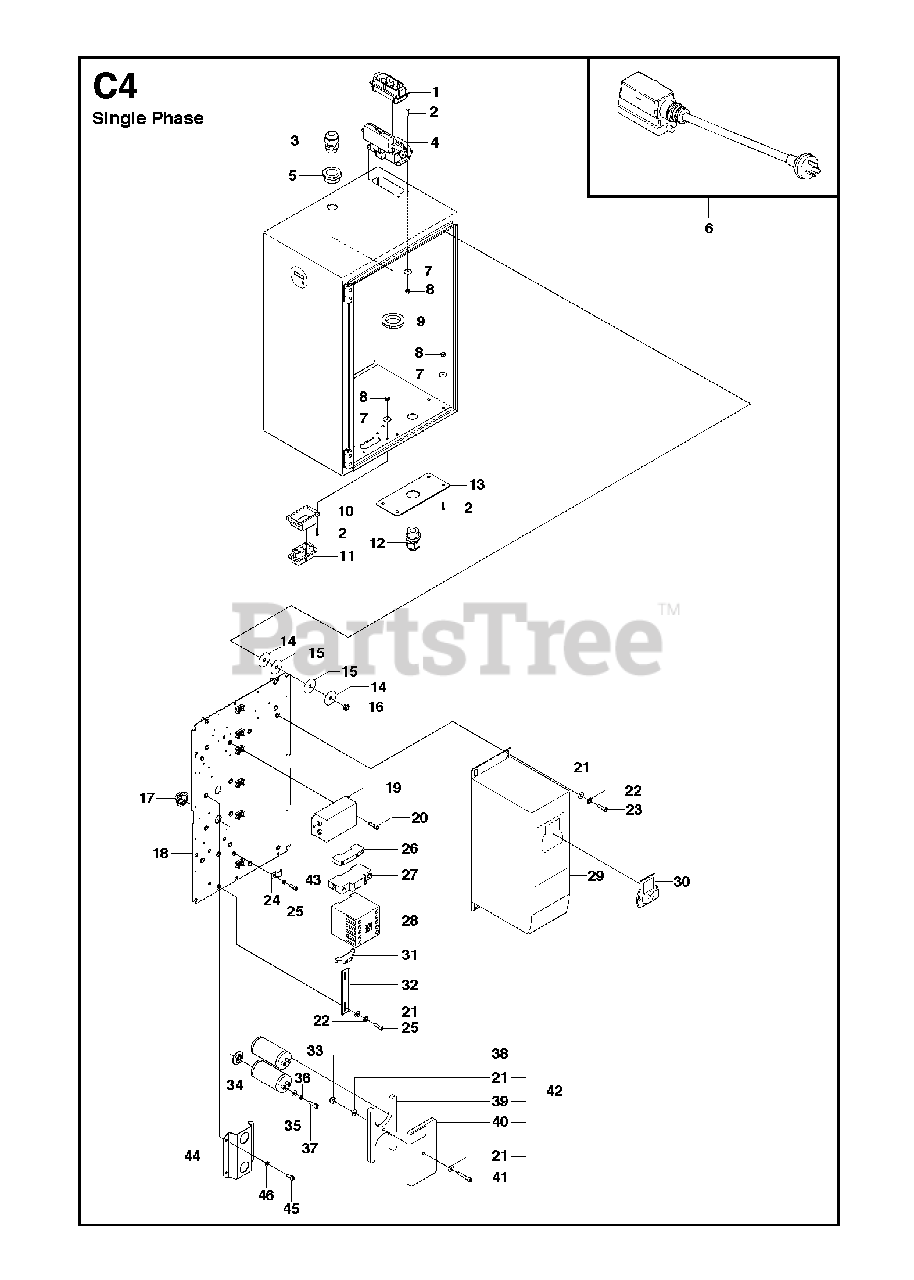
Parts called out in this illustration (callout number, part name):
2	SCREW CRPANM
8	HEXAGON LOCKING NUT
16	HEXAGON LOCKING NUT
33	CAPACITORFor machines before SN 2014 2200007
35	WASHER
36	SPRING WASHER
37	SCREW EHHM
38	HEXAGON LOCKING NUT
